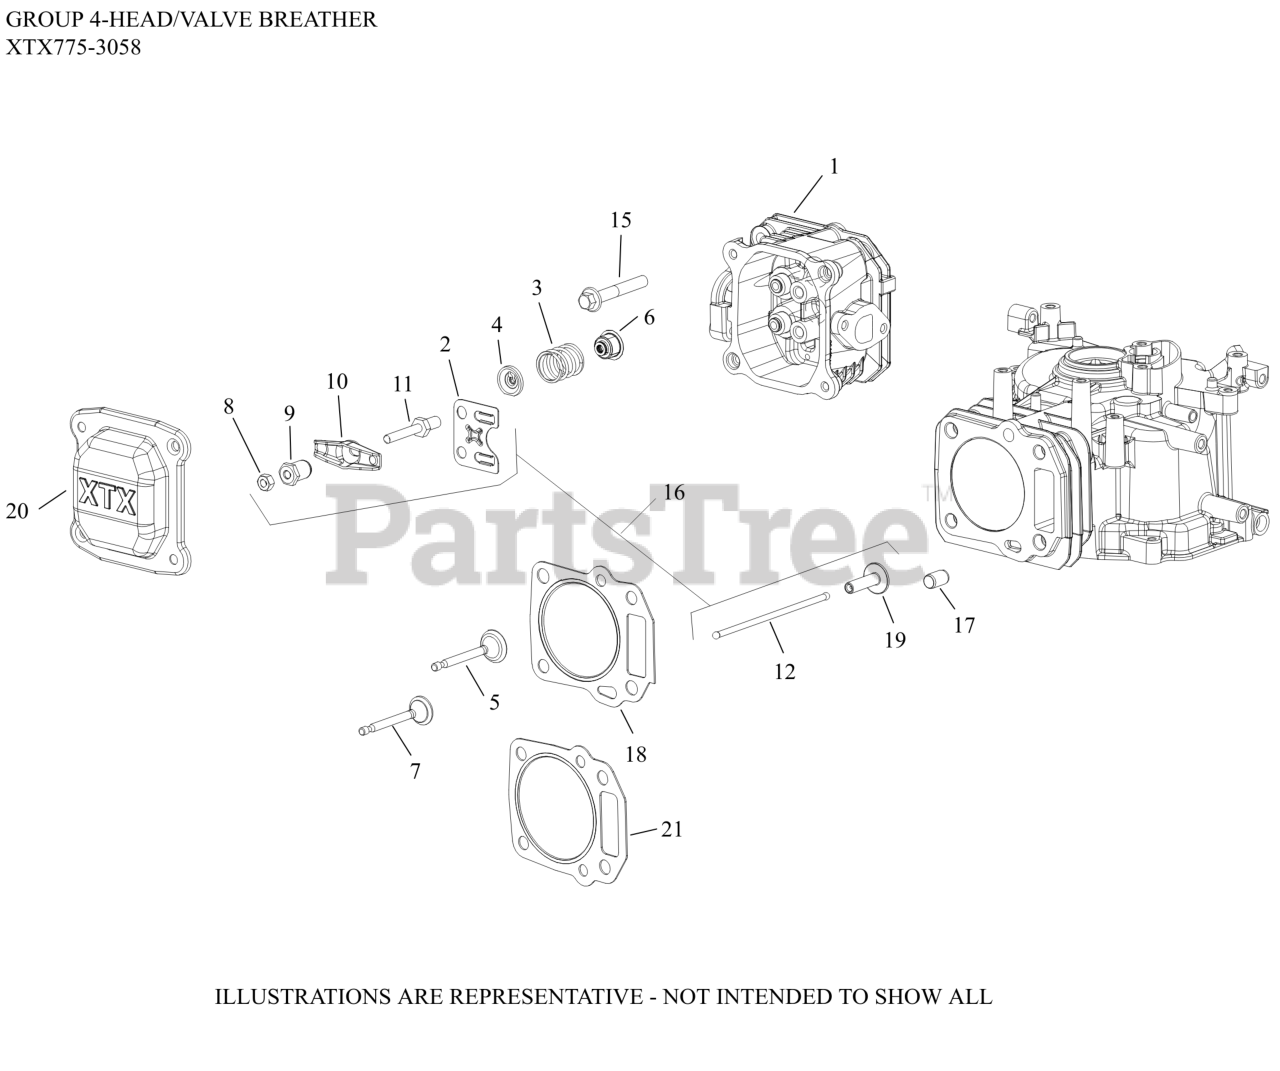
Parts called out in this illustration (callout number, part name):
1	HEAD, CYLINDER
2	PLATE, PUSHROD GUIDE
3	SPRING, VALVE
4	RETAINER, VALVE SPRING
5	VALVE, INTAKE
6	SEAL, VALVE STEM
7	VALVE, EXHAUST
8	NUT, HEX JAM
9	PIVOT, ROCKER ARM
10	ARM, ROCKER
11	STUD, ROCKER ARM
12	ROD, PUSH
15	SCREW, HEX FLANGE M8
16	KIT, VALVE TRAIN
17	DOWEL, CYLINDER HEAD
18	KIT, HEAD GASKET-USE 14 841 34-S (XT)
19	LIFTER, VALVE
20	COVER, VALVE
21	KIT, HEAD GASKET (CV173)
